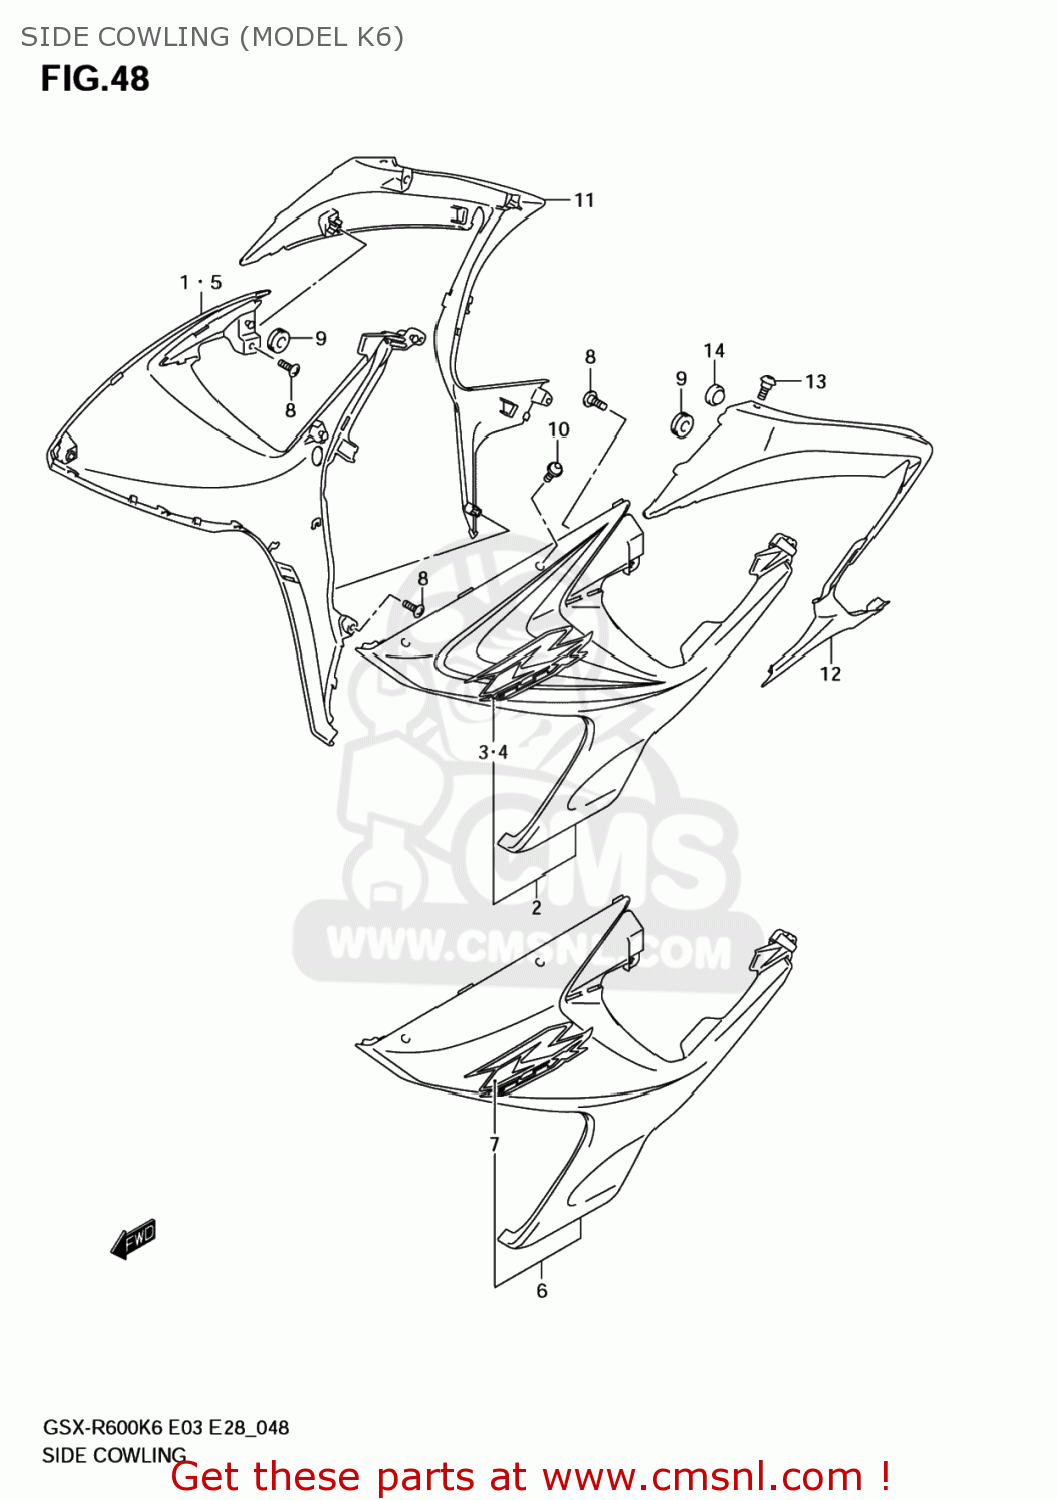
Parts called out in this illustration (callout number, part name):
1	COWLING,SIDE,R(WHITE)
2	COWLING,SIDE,L(WHITE)
3	TAPE,COWL SIDE,R
4	TAPE,COWL SIDE,L
5	COWLING,SIDE,R(BLACK)
6	COWLING,SIDE,L(BLACK)
7	EMBLEM,GSXR
8	SCREW
9	CUSHION
10	SCREW(5X13)
11	COVER,UNDER COWL,R
12	COVER,UNDER COWL,L
13	SCREW(5X16)
14	CUSHION
